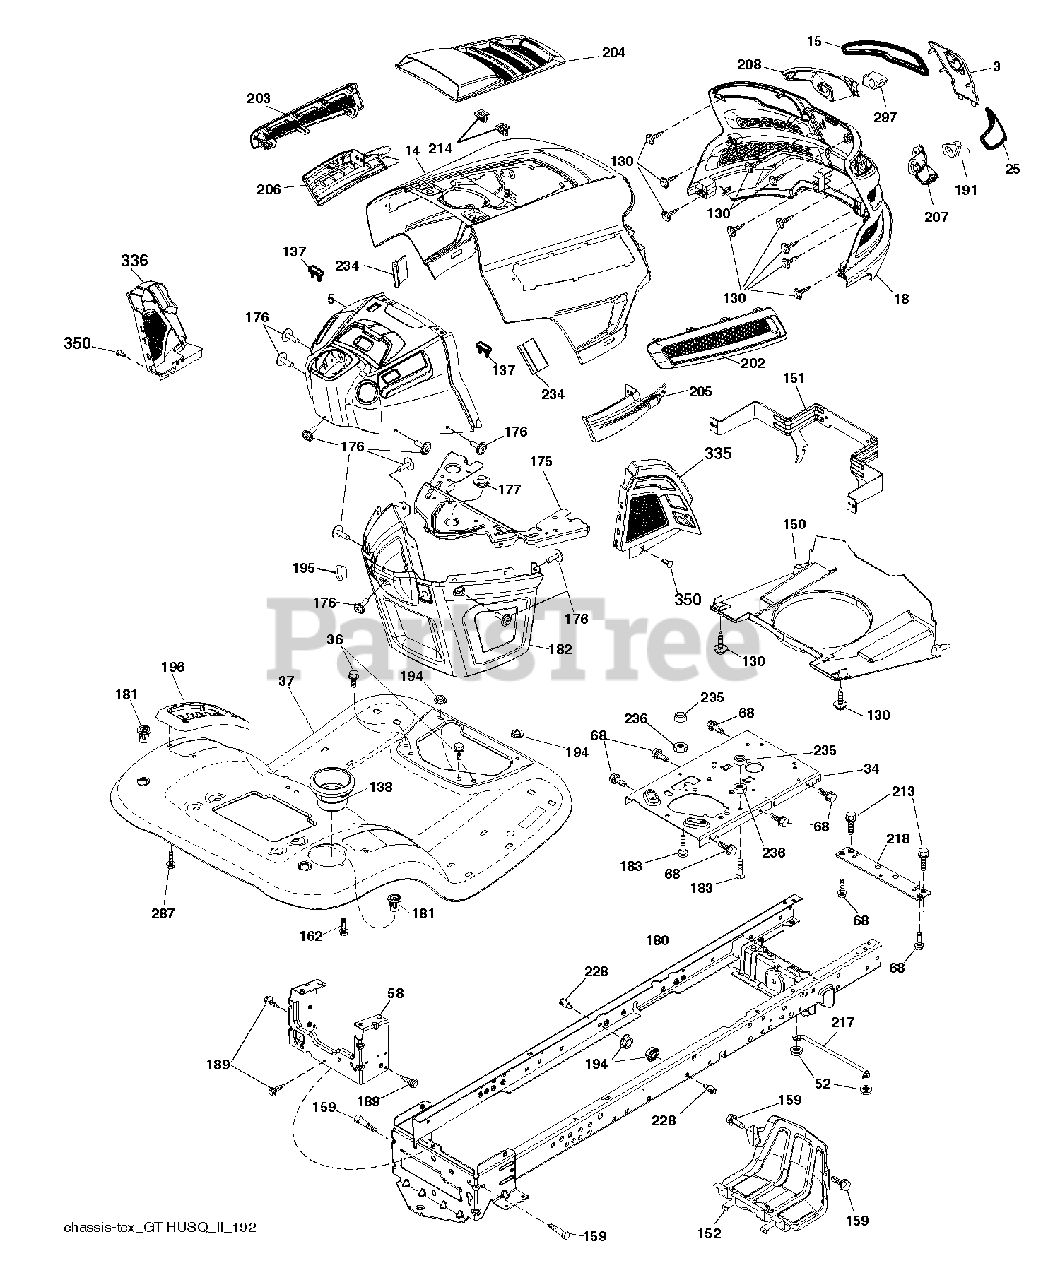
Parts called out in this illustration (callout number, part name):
3	APPLIQUE.SUBASM.GT.HUSQ.II
5	DASH.W/O.BUMPERS.RS.
14	HOOD.ASM.HUSQVARNA.GT.TEX.ORAN
15	LENS.HEADLIGHT.LH.GTII.2011
18	GRILLE.SUBSTRATE.2011.
25	LENS.HEADLIGHT.RH.GTII.2011
34	PLATE.ENGINE.WELDED.CHASSIS
36	SCREW 5/16"
37	FENDER.TLT.PDL.CNTRL.W/CPH.ORG
52	LOCKNUT
58	DRAWBAR UPPER 2PC SMALL FENDER
68	SCREW LT
130	SCREW.#10 X 0.750.BOS
137	BUMPER DASH
138	HOLDER.CUP.LT.GREY
150	AIR.DUCT.GTV.BLACK
151	BRACKET.PIVOT.HOOD.GT.HUSQ.II
152	SHIELD.BROWNING.PNT.GT.V2
159	SCREW, 3/8-16X3/4
162	SCREW.HI-LO.CONSOLE
175	PLATE.CROSSMEMBER.HUSQ
176	SCREW.#10-24X5/8.RN.QU
177	BUSHING STEERING
180	CHASS.WLDMNT.TL.12GA/2P.48/54
181	BUSHING.MNT.FEND.CRGO.TEX.49
182	DASH.LOWER.COMMON.12V.ADAPTOR
183	BOLT.5/16-18X1-1/4 FULL THD
189	SCREW
191	INSERT.REFLECTIVE.RH.HUSQ.GTII
194	NUT LOCK HEX FLANGE 5/16-18
195	PLUG.HOLE.DASH.LOWER.12V.BLK
196	CONSOLE.DECK.LIFT.GREY
202	VENT.SIDE.RH.GT.HUSQ.II.
203	VENT.SIDE.LH.GT.HUSQ.II.498
204	VENT.TOP.HUSQ.GT2
205	SIDE.TRIM.RH.GT.HUSQ.II
206	SIDE.TRIM.LH.GT.HUSQ.II.GRAY
207	BEZEL LIGHT.RH.GT.II.MYLAR
208	BEZEL LIGHT.LH.GT.II.MYLAR
213	BOLT
214	CLIP.RETAINER.TINNER.
217	ROD.PIVOT.HOOD
218	X-PIECE.HOOD.STOP.NON/
228	STUD.FASTNER.W/ANTI-ROTATE
234	BUMPER.HOOD.TEX.HUSQVARNA
235	SPACER FENDER
236	NUT.CENTERLOCK.5/16-
287	SCREW 1/4X20
297	INSERT.REFLECTIVE.LH.HUSQ.GTII
335	COVER.LOWER.DASH.RH.BLACK
336	COVER-LH.LOWER.DASH.GT2.BLACK
350	CLIP.X-MAS.TREE
